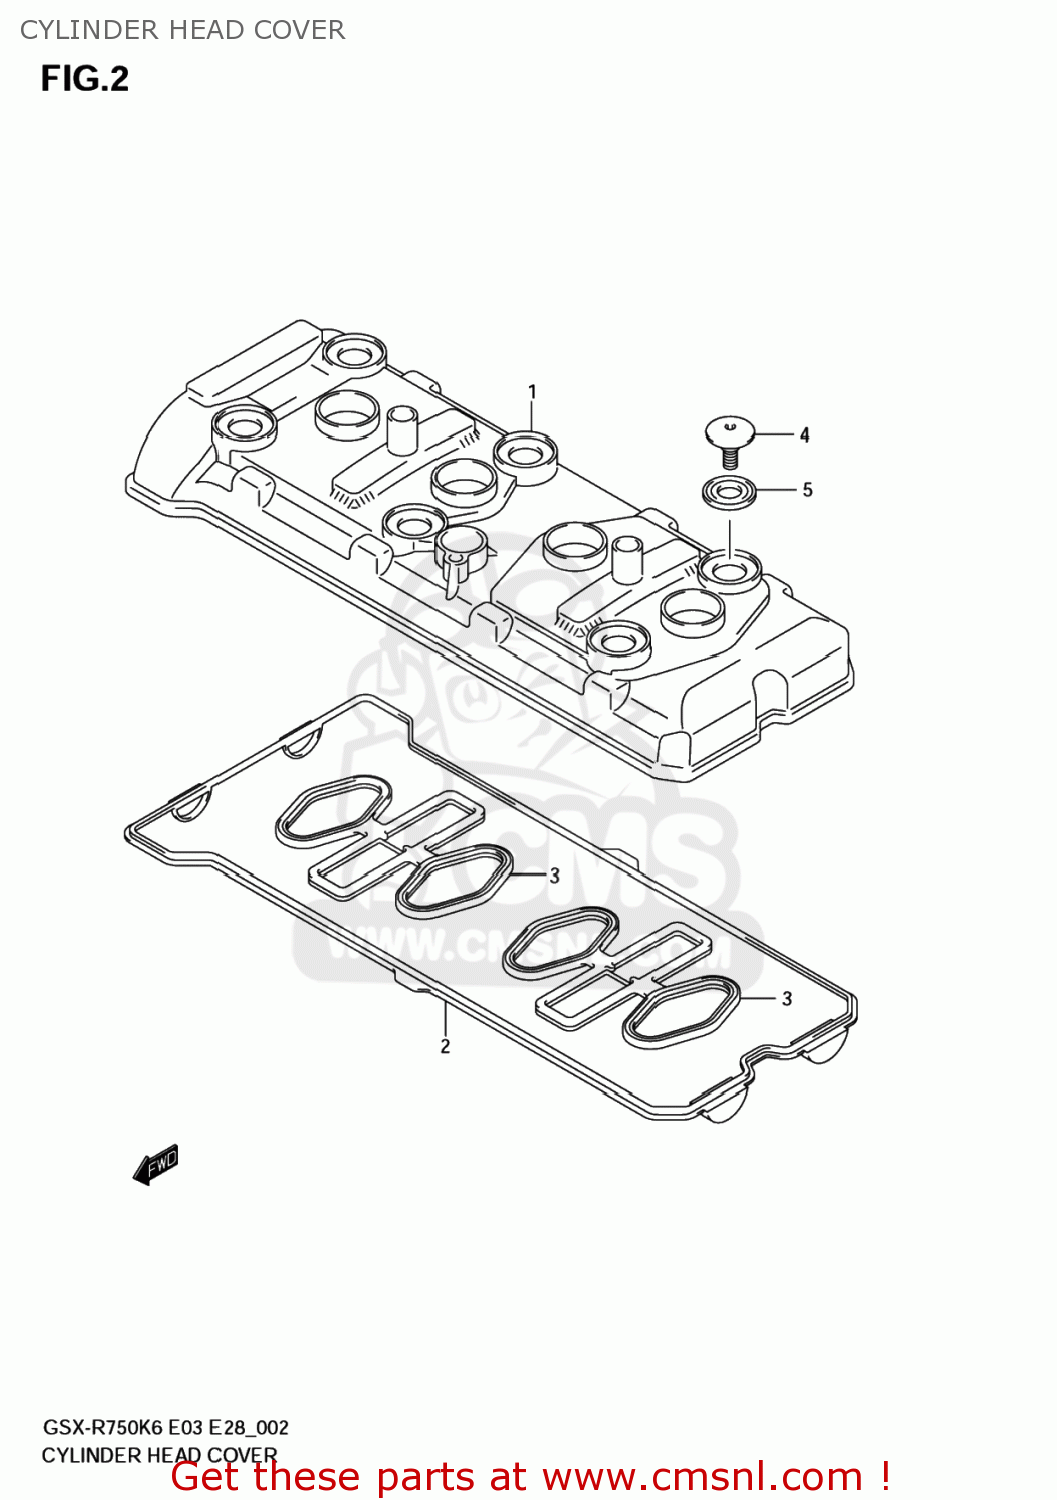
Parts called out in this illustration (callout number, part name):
1	COVER,CYLINDER HEAD
2	GASKET,CYL HEAD COVER NO.1 (NAS)
3	GASKET,CYL HEAD COVER NO.2 (NAS)
4	BOLT (7X5.5)
5	WASHER,CYL HEAD COVER
